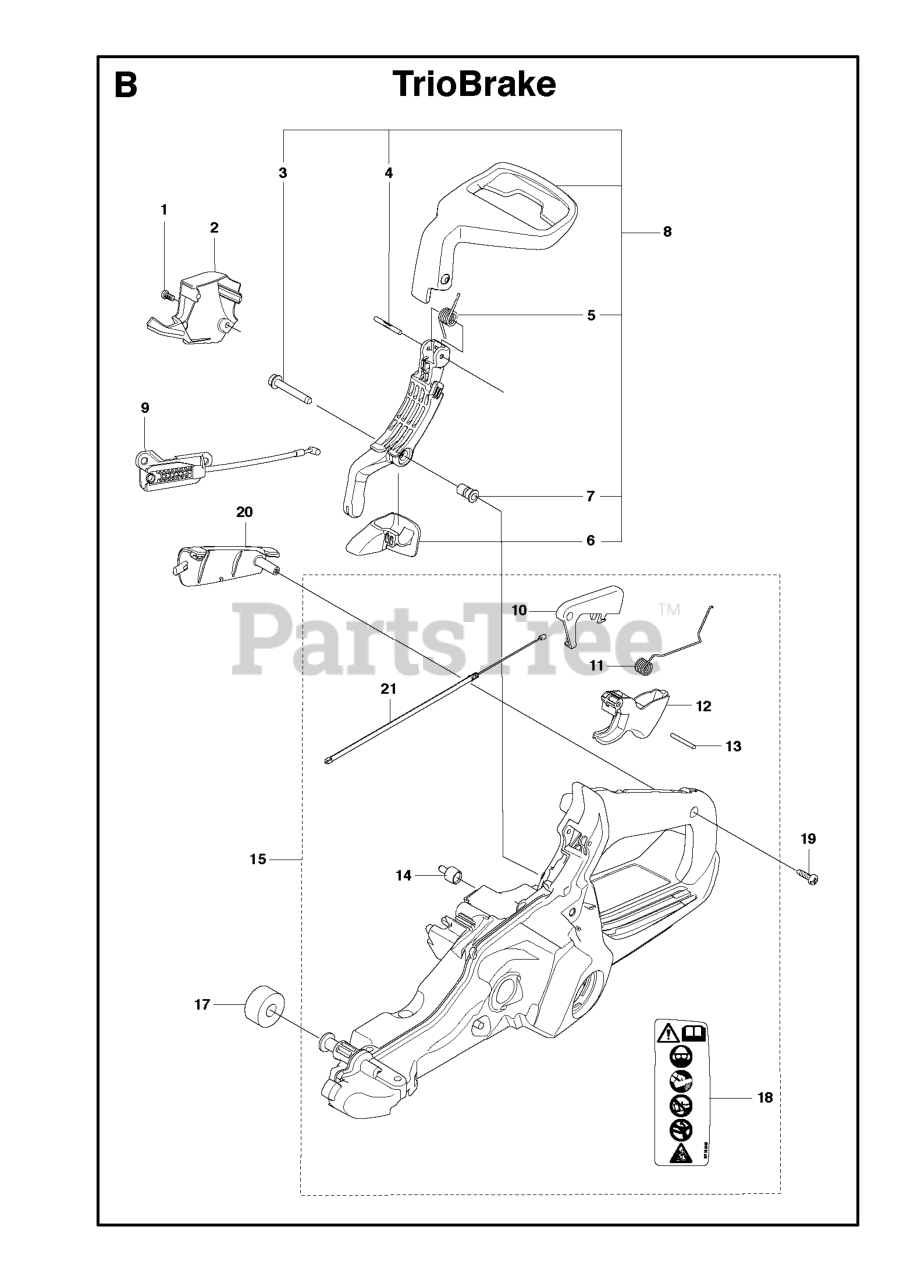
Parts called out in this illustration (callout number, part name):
4	GROOVED PIN
8	HAND GUARD ASSY
10	THROTTLE LOCKOUT
14	FUEL TANK VENT
15	FUEL TANK ASSY
17	DEFLECTION LIMITER
20	HANDLE INSERT
21	THROTTLE CABLE ASSY
